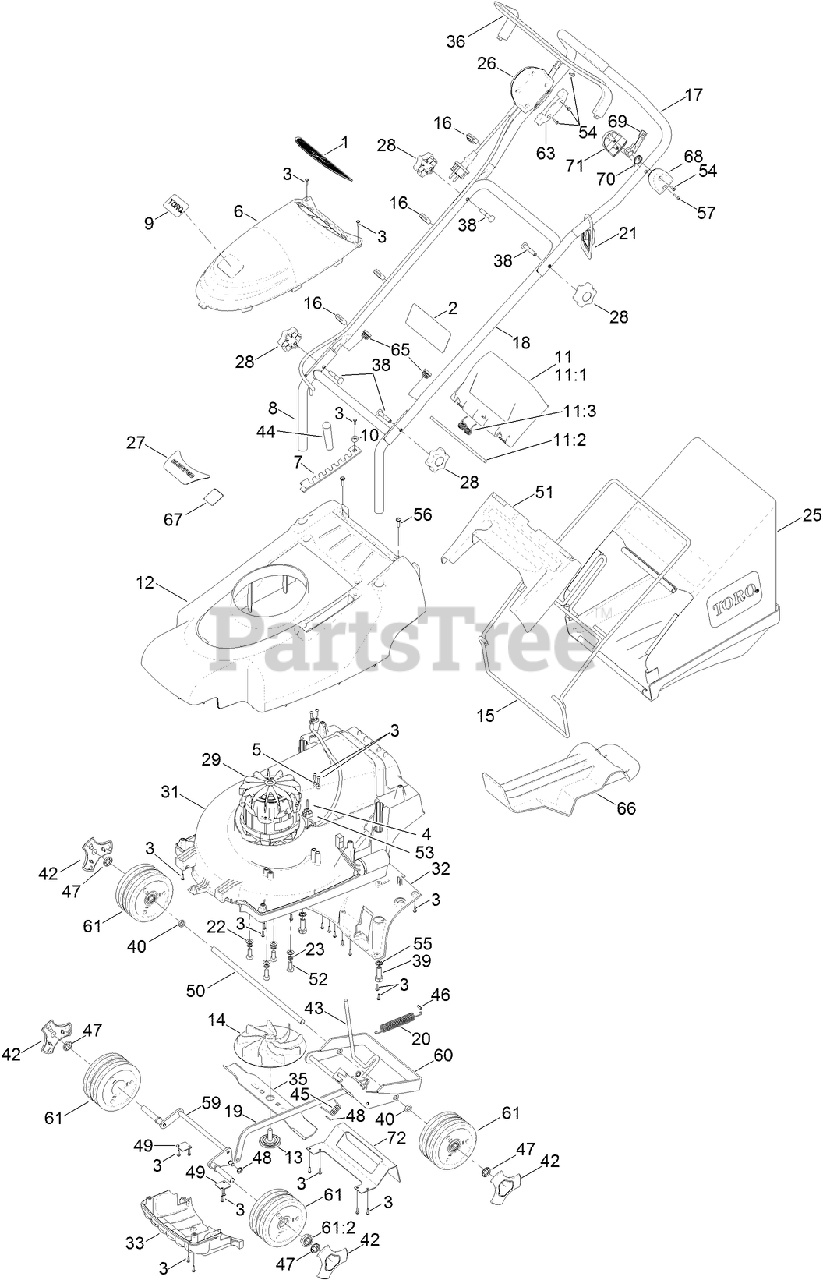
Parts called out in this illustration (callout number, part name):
1	MOULDING-VENT, SUPPORT
2	DECAL-SAFETY, ELECTRIC
5	CLAMP-CABLE
6	COVER-MOTOR
7	PLATE-HOC
8	HANDLEBAR-LOWER
9	DECAL-TORO
10	COVER-SCREW, HOC
11	Rear Flap ASM
11:1	DEFLECTOR-REAR
11:2	ROD-DEFLECTOR
11:3	SPRING-DEFLECTOR
12	COVER-TOP
13	BOLT-FIXING, CUTTERBAR (NYLON)
14	CARRIER-CUTTERBAR
15	FRAME-GRASSBAG
16	CLIP-CABLE
17	HANDLEBAR-UPPER
18	HANDLEBAR-MIDDLE
19	ROD-CONNECTING
20	SPRING-BALANCE, COUNTER
21	CLEAT-CABLE
22	WASHER
23	WASHER-SPRING
25	GRASSBAG
26	SWITCH AND LEAD ASM
28	KNOB-HANDLEBAR
31	UNDERDECK
32	THROWPLATE
35	CUTTERBAR
36	ARM-BAIL
38	BOLT-HANDLEBAR
39	SCREW-HH
40	SPACER-WHEEL, REAR
42	CAP-HUB
43	LEVER-HOC
44	KNOB-HOC
45	SPRING-HOC
46	PIN-SPRING, HOC
47	WASHER-STARLOCK
48	WASHER-STARLOCK
49	PLATE-PIVOT, AXLE
50	ROD-AXLE, REAR
51	TOP-GRASSBAG
52	BOLT-MOTOR
53	BLOCK-TERMINAL
55	WASHER
56	SCREW
57	SCREW-PPH
59	FRONT AXLE ASM
60	REAR AXLE ASM
61	WHEEL ASM
61:2	BEARING-WHEEL
63	SWITCH-LEFT, LOWER
65	PLUG-TUBE
66	PLUG-MULCHING
67	DECAL-HOC
68	MOUNT-LEFT
69	LEVER-MOUNT
70	SPRING-BAILARM
71	MOUNT-RIGHT
72	GUARD-PLATE, AXLE
